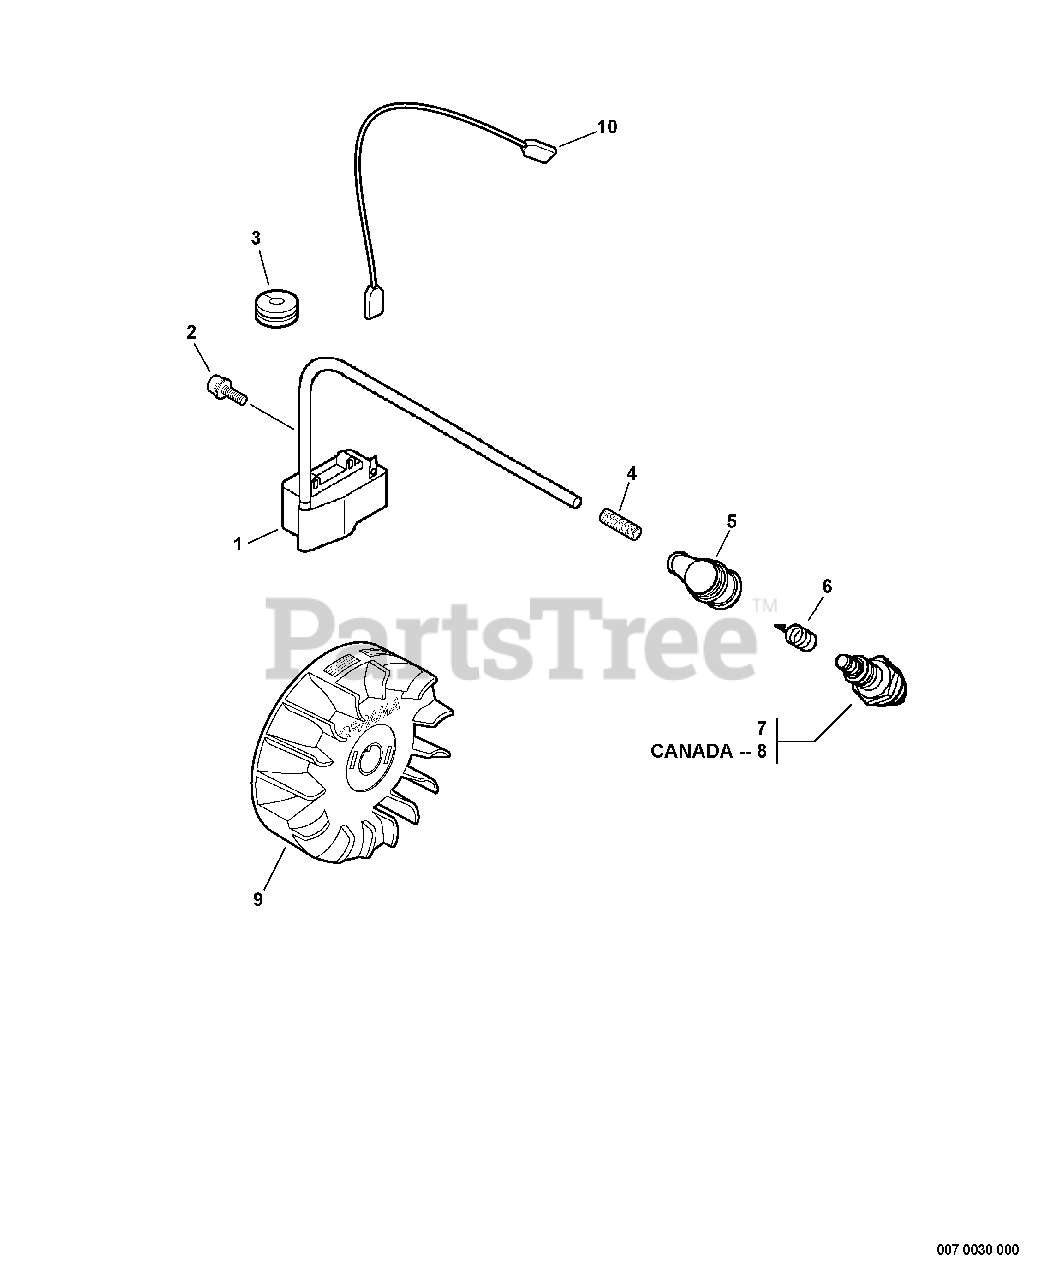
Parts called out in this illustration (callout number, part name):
1	COIL, IGNITION
2	SCREW - 4X20
3	GROMMET
4	TUBE, INSULATOR
5	CAP, SPARK PLUG
6	TERMINAL, SPARK PLUG CAP
7	SPARK PLUG -- BPM-8Y
8	SPARK PLUG -- BPMR-8Y
9	FLYWHEEL
10	LEAD - GROUND
